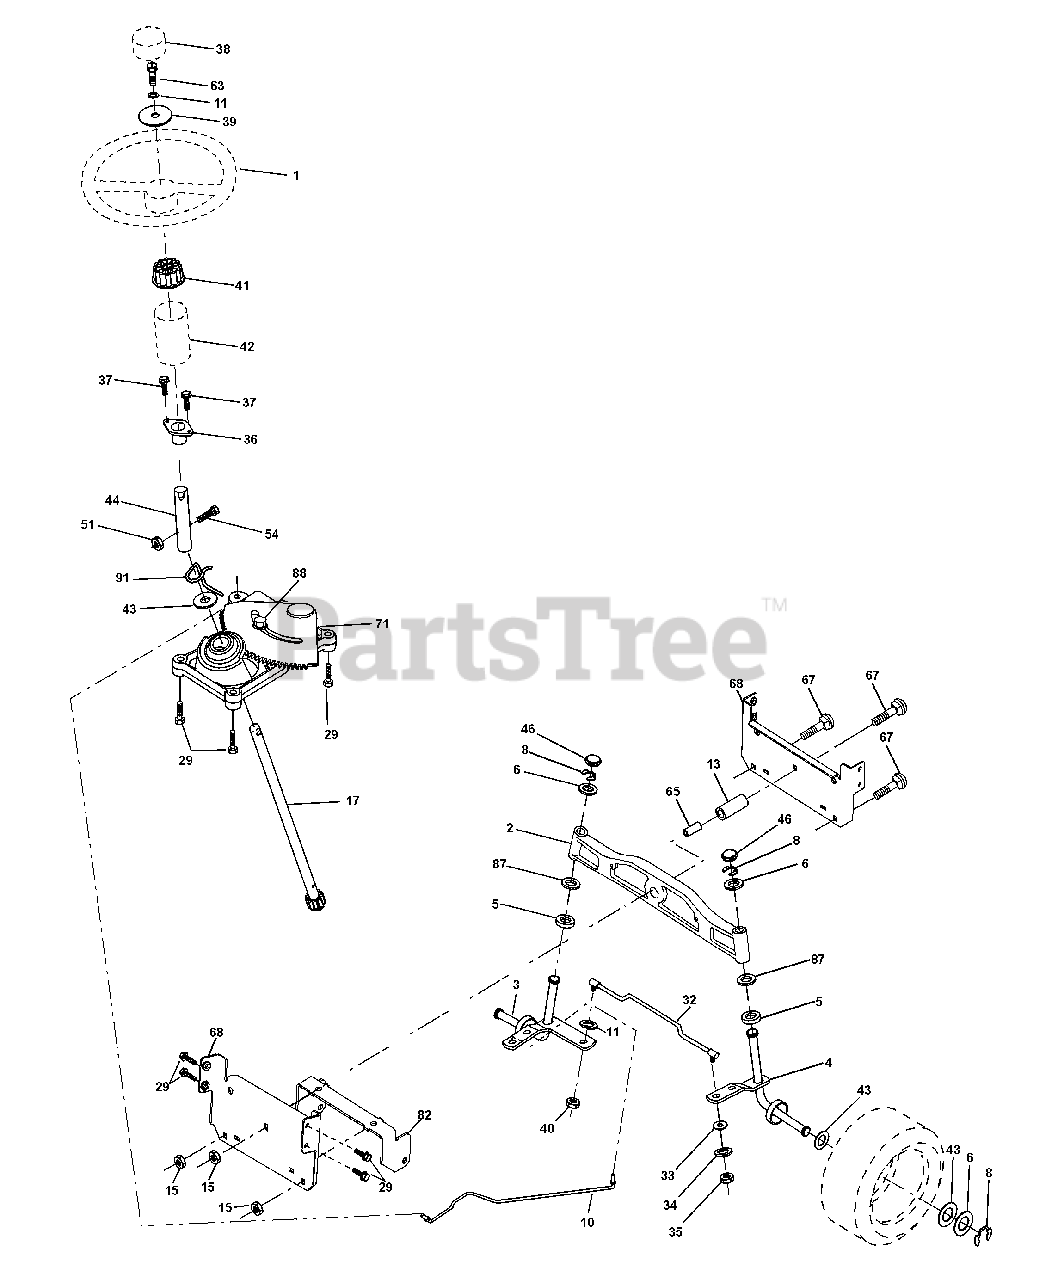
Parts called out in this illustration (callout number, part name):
1	Wheel Steering
2	Axle Cast LT Machined
3	Spindle Asm Cast LH
4	Spindle Asm Cast RH
5	Bearing Race Thrust Harden
6	Washer 25/32 X 1-5/8 X 16 Ga
8	Ring Klip #t5304-75
11	Washer Lock Hvy Hlcl Spr 3/8
13	Spacer Brg Axle Front
15	Nut Hex Flange Lock Yel D
17	Shaft Asm Strg Private Label
29	Screw 3/8-16x3/4
33	Washer 11/32 x 3/4 x 16 Ga.
34	Washer Lock Hvy. Helical 5/16 SD
35	Crownlock Nut 5/16-24 Unf
36	Bushing Strg
37	Screw TT #32.5 x 5 x 3/8 Flange
38	Cap Wheel Steer
39	Washer 13/32 x 1-1/20 x 11 Ga.
40	Nut Lock Center 3/8-24 Unf
41	Adaptor Wheel Strg
42	Boot Dash Steering
43	Washer 25/32 X 1 1/4 X 16 Ga
44	Extension Steering Non-adjust
46	Cap Spindle Fr Top Blk
51	Nut Lock Hex W/Ins 5/16-18 UNC
54	Bolt Fin Hex 5/16-18 UNC x 1-1/4
63	Bolt Fin Hex 3/8-16 UNC x 1 Gr. 5
65	Spacer, Brace Axle
67	Bolt Rdhd 3/8-16 x 2-1/4
68	Brace, Axle
71	Steering Asm.
82	Bracket Susp Chassis Front 15"
87	Washer Flat .781 x 1-1/2 x .14
88	Bolt Shoulder 7/16-20 Unc Tap R
91	Cap Steering
